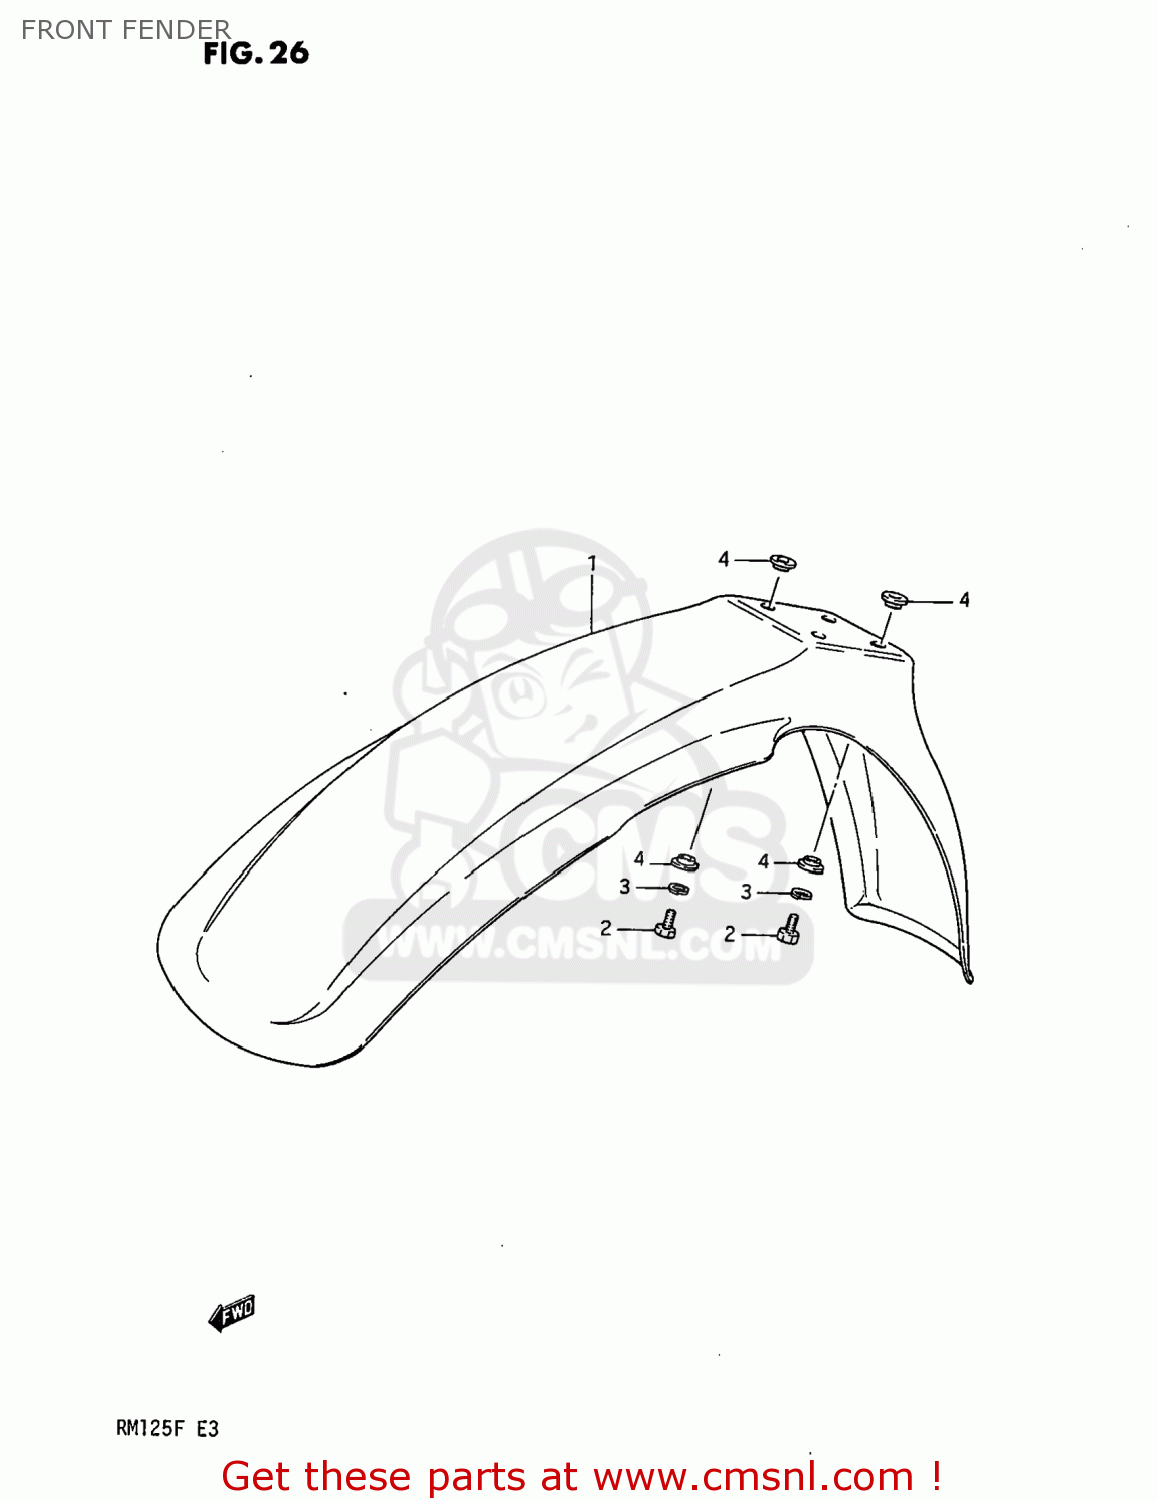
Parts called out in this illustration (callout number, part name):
1	FENDER,FRONT
2	BOLT, UPPER
3	LOCK WASHER
4	SPACER
